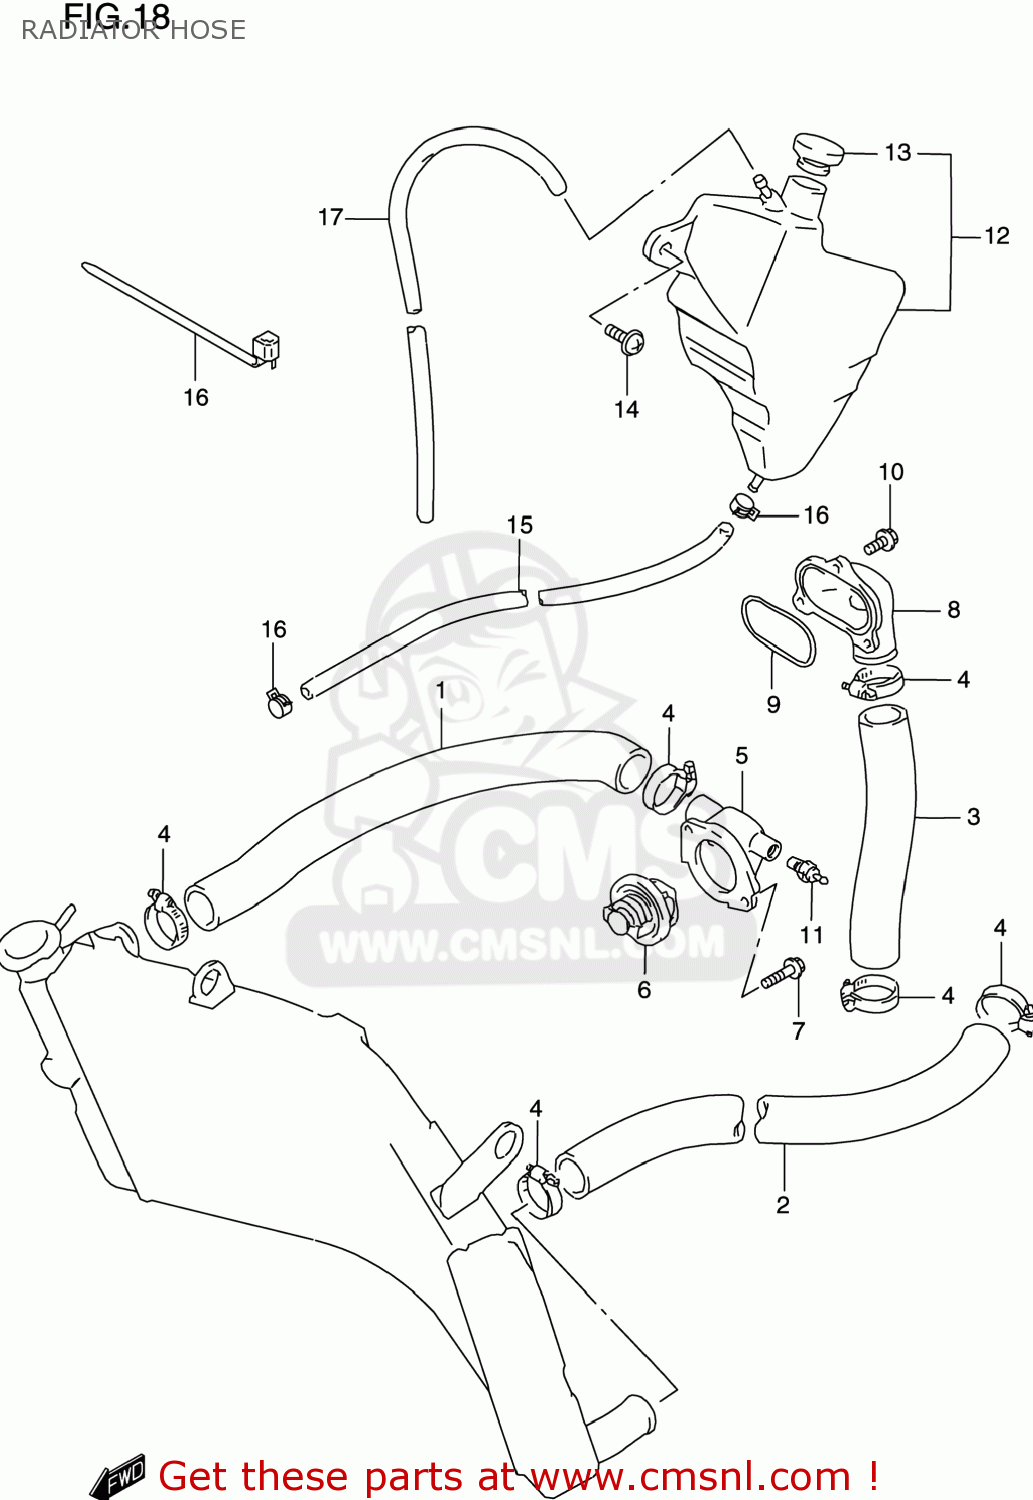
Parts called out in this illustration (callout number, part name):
1	HOSE,RADIATOR INLET
2	HOSE,RADIATOR OUTLET
3	HOSE,CYLINDER INLET
4	CLAMP
5	CONNECTOR,THERMOSTAT INLET
6	THERMOSTAT,WATER
7	BOLT
8	CONNECTOR,CYLINDER WATER,INTAKE
9	O RING,CYL WATER CONNECTOR
10	BOLT
11	GAUGE ASSY,WATER TEMP
12	TANK ASSY,RESERVOIR
13	CAP,RESERVOIR TANK
14	SCREW(6X20)
15	HOSE,RESERVOIR TANK INLET
16	CLIP
17	HOSE,RESERVOIR TANK OUTLET
18	CLAMP L:165
